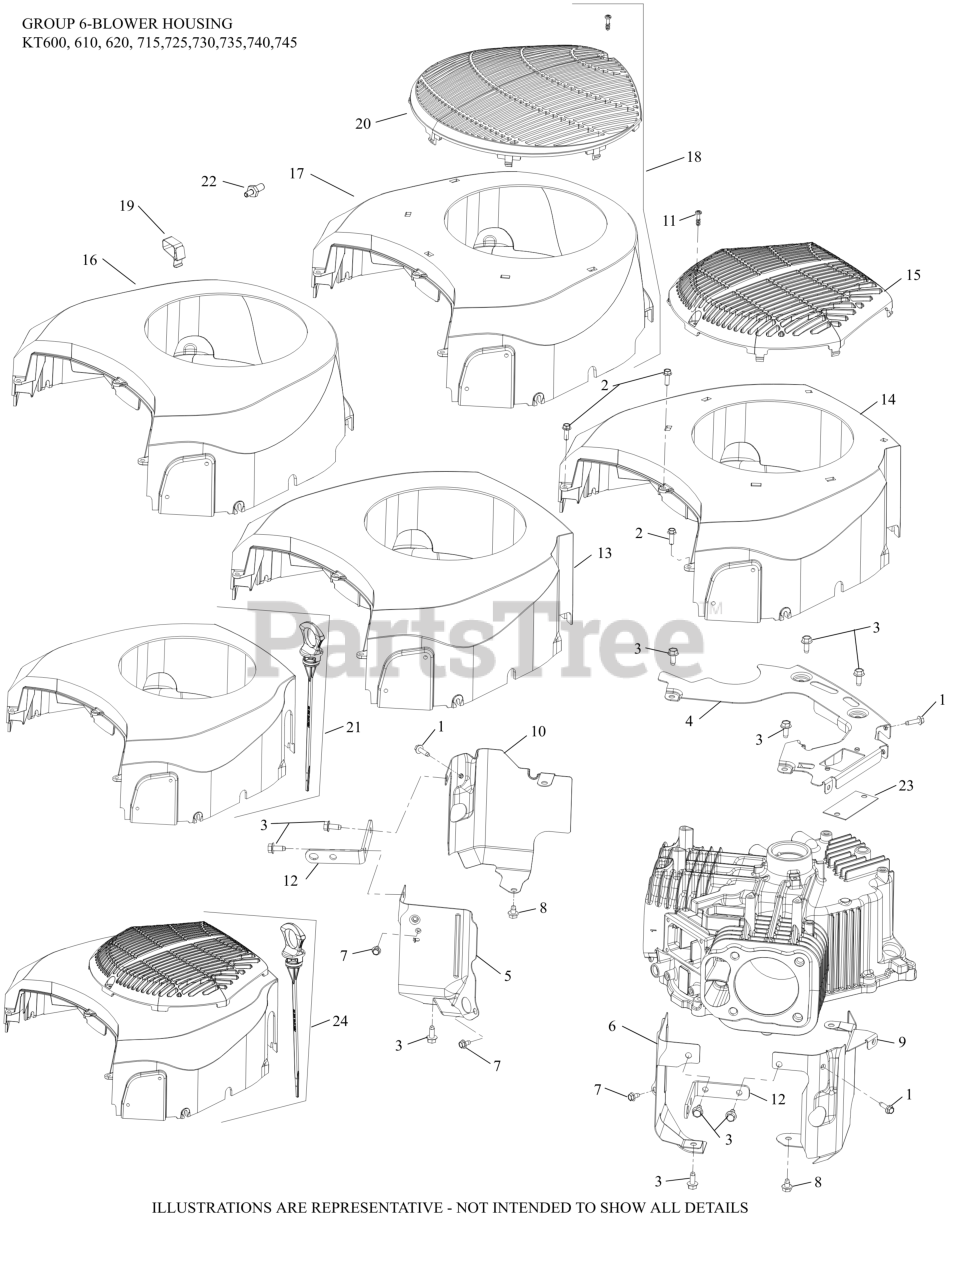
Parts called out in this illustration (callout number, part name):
1	SCREW, THD FRM-USE 25 086 473-S
2	SCREW, HI-LOW
3	SCREW, THREAD FORMING
4	PLATE, BACKING
5	BAFFLE, VALLEY #1
6	BAFFLE, VALLEY #2
7	SCREW, THREAD FORMING
9	BAFFLE, LEFT BARREL
10	BAFFLE, RIGHT BARREL
11	SCREW, M5-2.42 (PT) THREAD
12	STRAP, LIFTING
14	KIT, BLOWER HOUSING
15	GUARD, FIXED
19	CLIP, BLOWER HOUSING
22	BOLT, ENGINE GROUND
